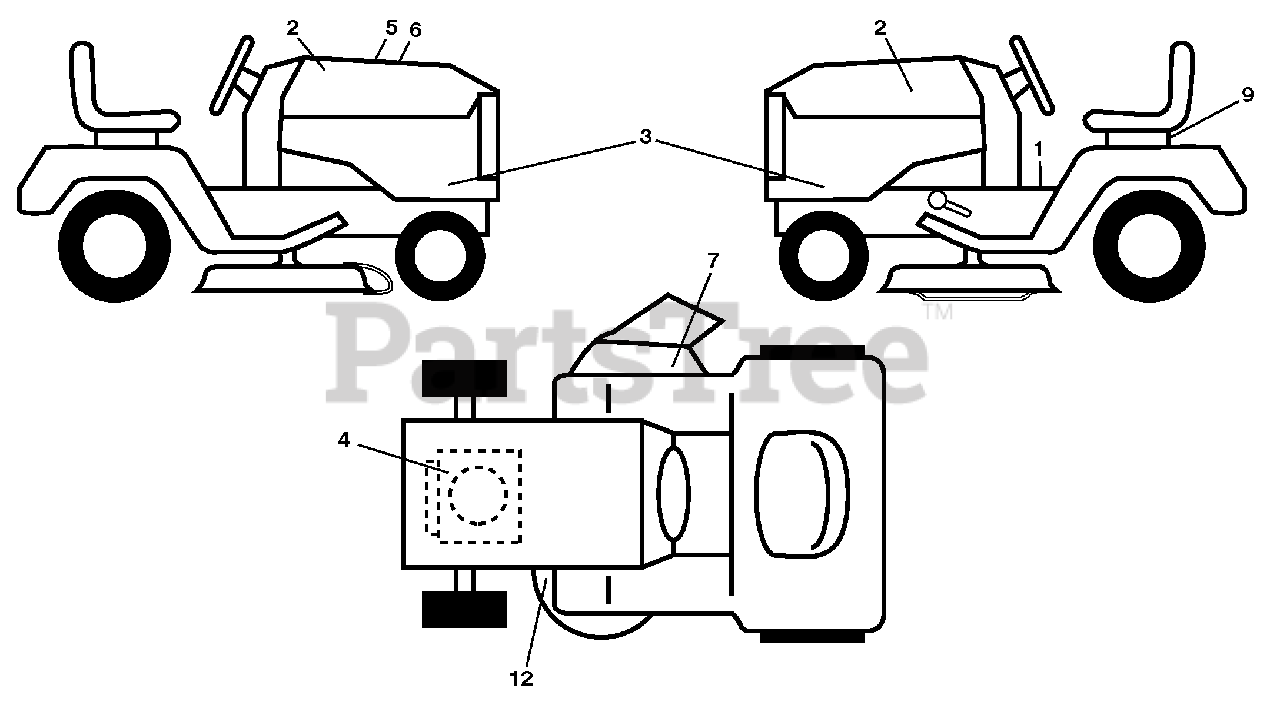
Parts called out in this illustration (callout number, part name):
1	Decal, Fender Warning
2	Decal, Hood
3	Decal, Hood Panel SD
4	Decal, Engine H.P.
5	Decal, Customer Respons.
6	Decal, Replacement
7	Decal, Mower Warn. Keep Hands Away
9	Decal, Battery Dnge/Poi
12	Decal, Mower V-Belt Schematic
